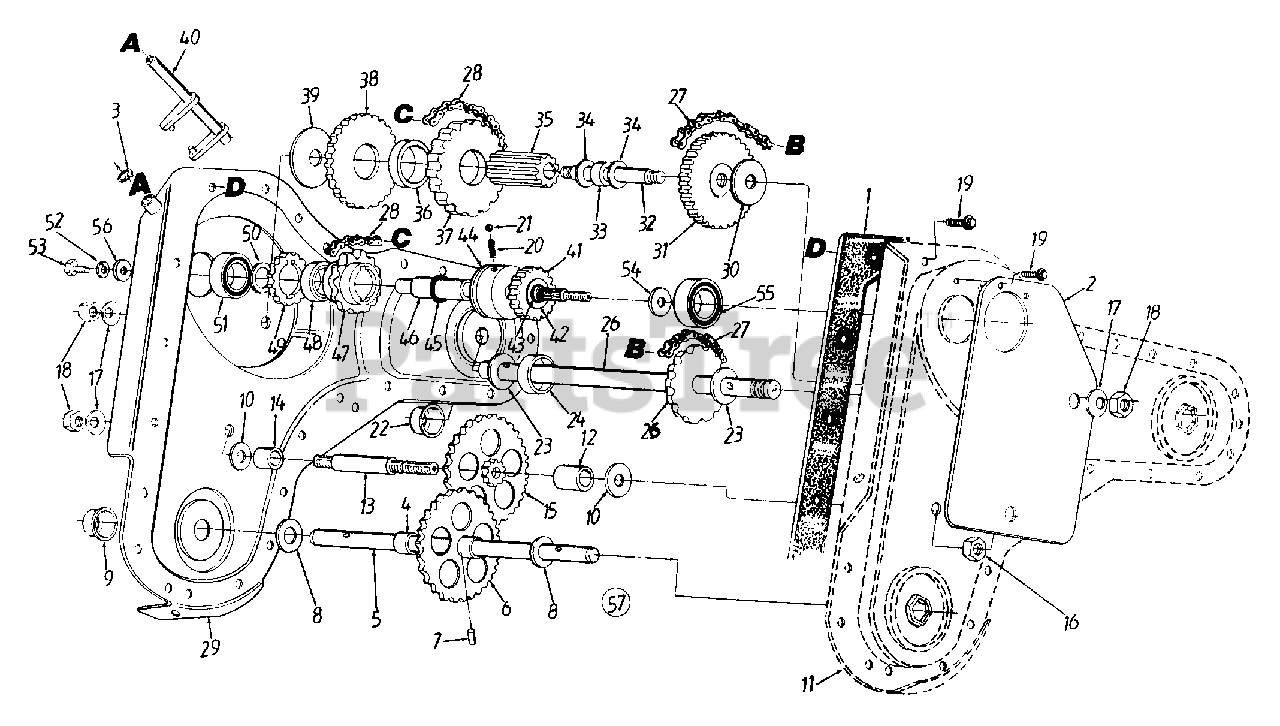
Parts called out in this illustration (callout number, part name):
1	Chain Case Gasket
4	Spacer .735" I.D. x .886" O.D.
5	Wheel Shaft
6	Spur Gear 46T
7	Pin Type "E" Grooved
8	Fl-Wash. .76" I.D. x 1.5" O.D.
9	Dust Cover Ass'y. .75" Shaft
10	Fl-Wash. 7/16" I.D. x 1-3/8" O.D.
13	Jack Shaft 2.06" Lg.
14	Spacer .635" I.D. x 1" O.D. x .37" Thk.
15	Gear Idler Ass'y.
16	Hex Patch L-Nut 7/16-20 Thd.
17	Bell-Wash. .45" I.D. x 1" O.D.
18	Hex Nut 7/16-20 Thd.
19	Hex Wash. Hd. TT-Tap Scr. 1/4-20 x .5" Lg.
20	Spring Detent
22	Dust Cover Ass'y. 1" Shaft
23	Thrust Wash. 1.03" I.D. x 1.62"
24	Spacer 1" I.D. x 2" O.D. x .5" Thk.
26	Tine Shaft Ass'y.
27	Chain #50 5/8" Pitch x 52 Links - Endless
28	Chain - #41 1/2" Pitch x 30 Links - Endless
30	Fl-Wash. 7/16" I.D. x 1-3/8" O.D.
31	Gear and Sprocket Ass'y.
32	Jack Shaft 5" Lg.
33	Spacer .636" I.D. x .86" O.D.
34	Fl-Wash. .63" I.D. x .94" O.D.
35	Spur Gear 10T
36	Spacer 1.5" I.D. x 1.76" 0 D.
37	Sprocket - #41 Chain
38	Reverse Gear 46T
39	Thrust Wash. .445" I.D. x 1.92"
40	Shifter Ass'y.
41	Spur Gear 17T
42	Fl-Wash. .69" I.D. x 1.06" O.D.
43	Retaining Ring .669" Shaft
44	Clutch Collar
45	Retaining Ring .875" Shaft
46	Drive Shaft
47	Sprocket 11T
48	Neutral Spacer
49	Spur Gear 16T
50	Fl-Wash. 5/8" I.D. x 1" O.D.
51	Ball Bearing .669" I.D.
52	L-Wash. 1/4" I.D.
53	Hex Bolt 1/4-20 x .62" Lg.
54	Fl-Wash. .635" I.D. x 1" O.D.
55	Ball Bearing
56	Fl-Wash. .281" I.D. x .875" O.D.
57	Gear Case Ass'y. Comp.
